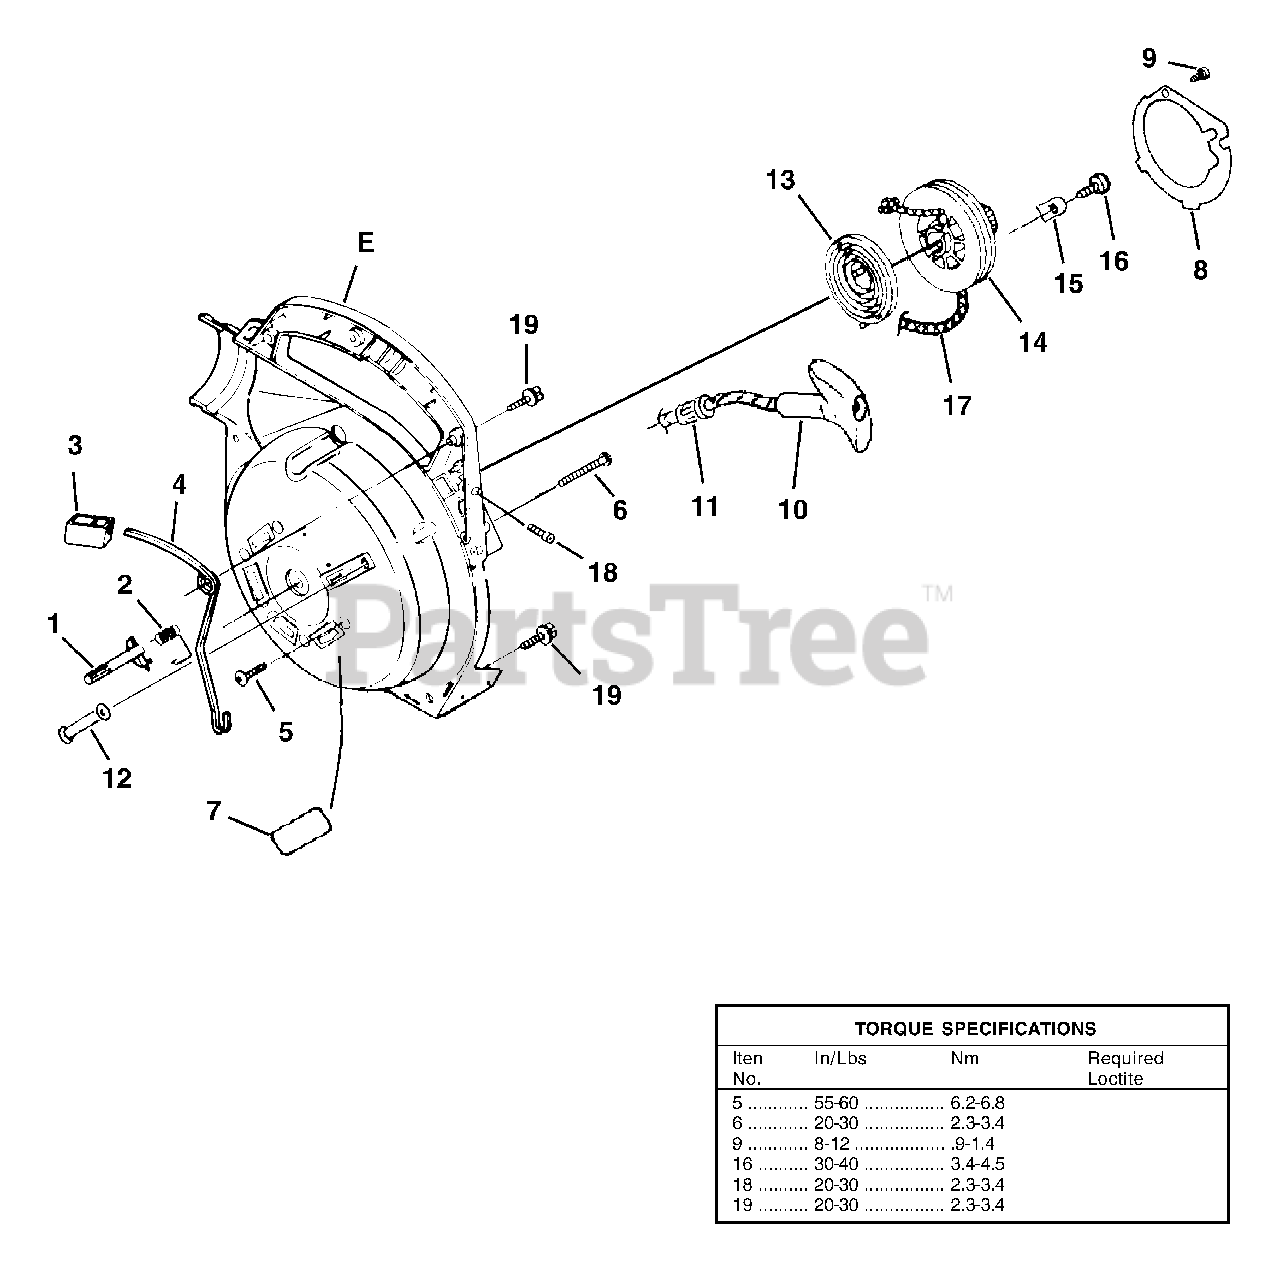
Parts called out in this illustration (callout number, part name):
1	LATCH-Throttle
2	SPRING-Throttle Latch
3	TRIGGER-Throttle
4	LEVER-Throttle
5	SCREW-Thread Form. (10-24 X 3/4")
6	SCREW-Thread Form. (#10 X 1 5/8")
7	KIT-Sealing
8	PLATE-Rotor
9	SCREW-Thread Form. (#6 X 1 3/8")
10	GRIP-Starter (Yellow)
11	BUSHING-Starter
12	GUIDE-Starter Rope
13	SPRING & CONTAINER
14	PULLEY-Starter
15	BRACKET-Retaining
16	SCREW-Thread Form. (#10 X 1/2")
17	ROPE-Starter
18	SCREW-Phil. Hd. (8-32 X 5/8")
19	SCREW-Thread Form. (10-24 X 3/4")
E	VOLUTE HOUSING & STARTER
